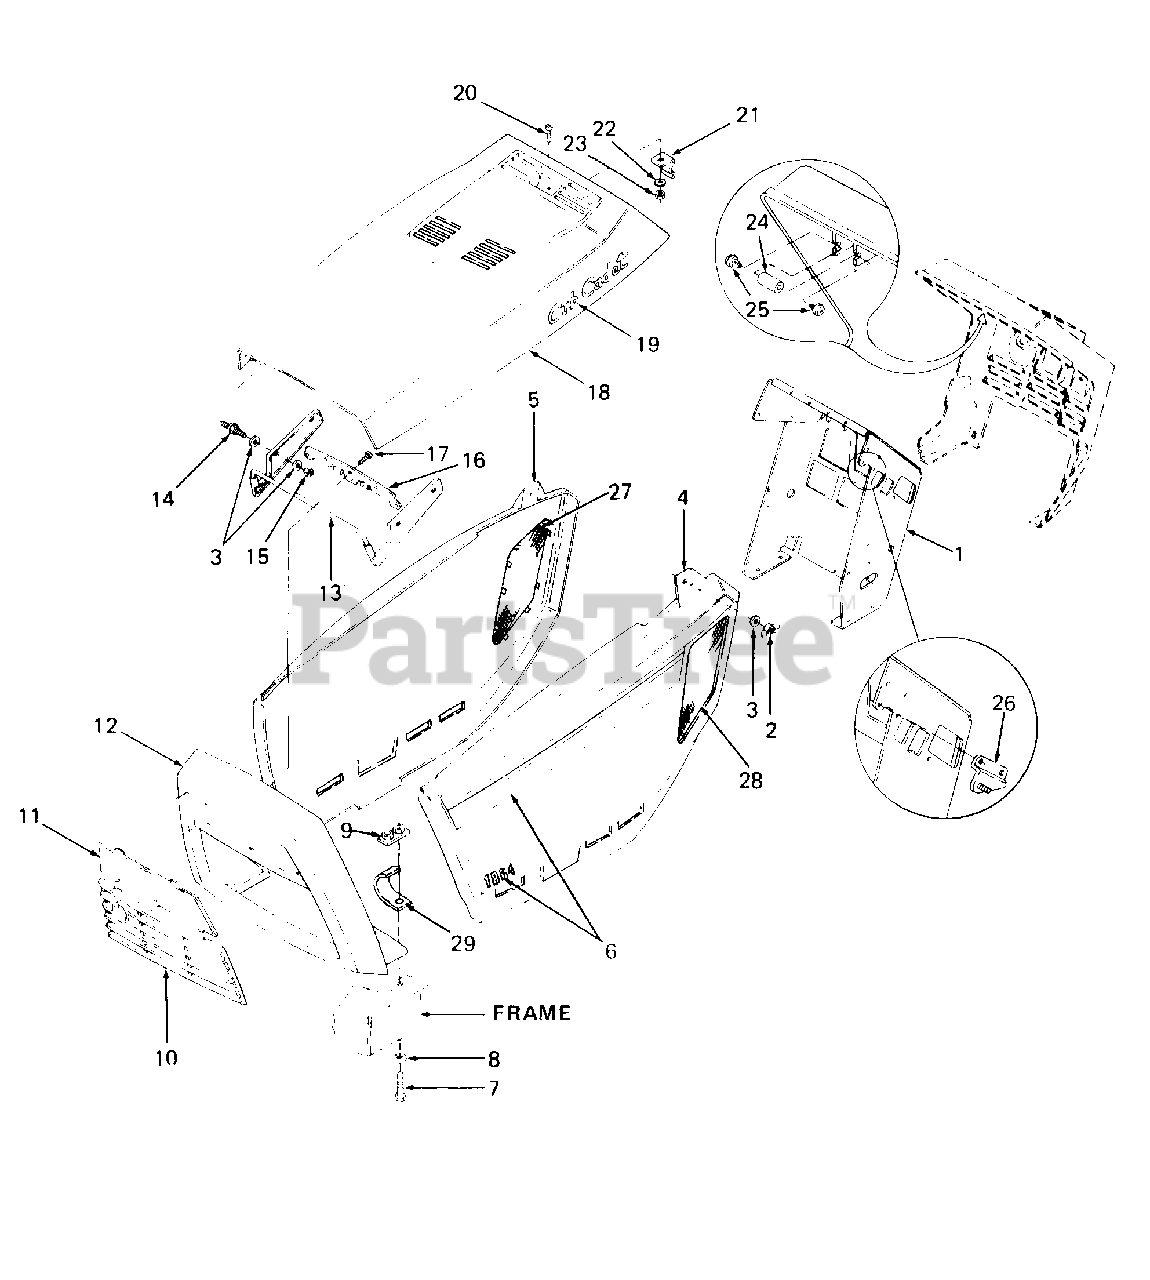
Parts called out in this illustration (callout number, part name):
3	Washer, Flat, .251 X.62 X.052 Thk
4	Panel, LH Side
5	Panel, RH Side
6	Graphics Kit, LH Side Panel
7	Screw, Hex Cap, 5/16-18 X 1.0 Lg GR5
8	Washer, Lock, 5/16
10	Grille, Insert
11	Grille, Lens
12	Grille w/Label
15	Nut, Hex Patch Lock, 1/4-20
18	Hood
19	Graphic, Cub Cadet Script w/Studs
20	Screw, Truss Hd, #8-32 X .38 Lg w
21	Clip, Hood Latch
22	Washer, Flat, .16 X .38 X .045 Thk
23	Nut, Hex Keps, #8-32
24	Pin, Latch
25	Screw, Phillips Hd Truss Mach 1/4-20 X .50 Lg
